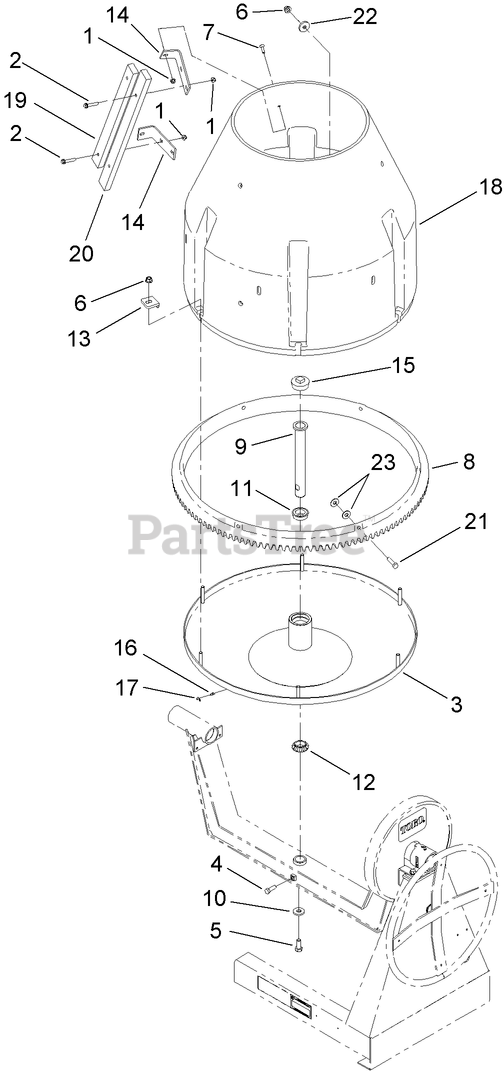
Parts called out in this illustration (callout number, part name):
1	NUT-HF, NI
2	SCREW-HHF
4	SCREW-HH
5	SCREW-HH
6	NUT-LOCK
7	SCREW-HSFH
8	GEAR-RING
9	SPINDLE
10	WASHER-FLAT
11	BEARING
12	BEARING-ROLLER
13	CLAMP-DRUM
14	BRACKET-PADDLE
16	FITTING
17	CAP-PLUG
18	DRUM
19	PADDLE
20	PADDLE
21	SCREW-HH
22	WASHER-FLAT
23	WASHER-FLAT
